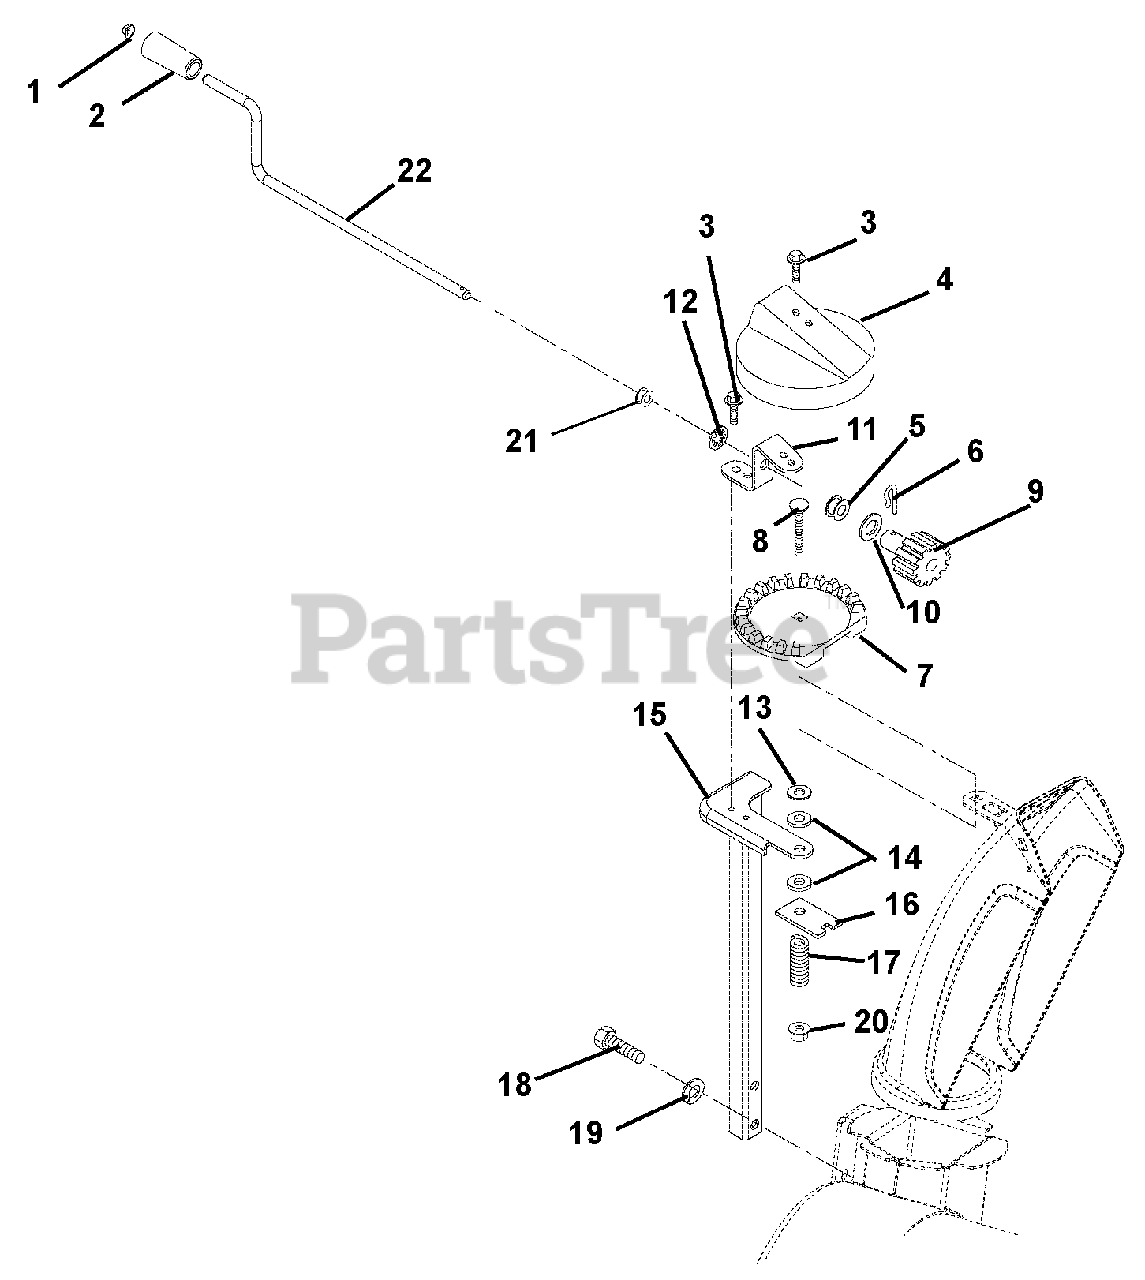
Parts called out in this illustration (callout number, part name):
1	CAP, 3/8 ROD YWZC
2	KNOB, CHUTE CRANK
3	SCR-TAP .25-20X.50 HWH TR YWZ
4	GEAR COVER
5	BUSHING, POLYLINER-.63 SNAPIN
6	PIN, SPRING CLIP
7	CHUTE GEAR
8	@BLT-RDHDSQNK .38-16X2.50 G5YZ
9	PINION GEAR W/BRACKET
10	WSHR-THRST .625 X 1.0 X .03
11	BRACKET, PINION GEAR
12	PUSHNUT .625
13	WSHR-FL-STL .380X1.50X.062 YWZ
14	FRICTION WASHER
15	CHUTE PEDESTAL, TALL COMPACT
16	PLATE, FRICTION
17	SG-COMP .187X.56X1.62
18	@BLT-HEX .38-16X1.75 GR5 YWZC
19	@WSHR-LK .38X.094 REG YWZC
20	@NUT-LK-TOP-FLG .38-16 YWZC
21	BUSHING, POLYLINER-.38 SNAPIN
22	CHUTE CRANK,COMPACT 920,XXX HI
